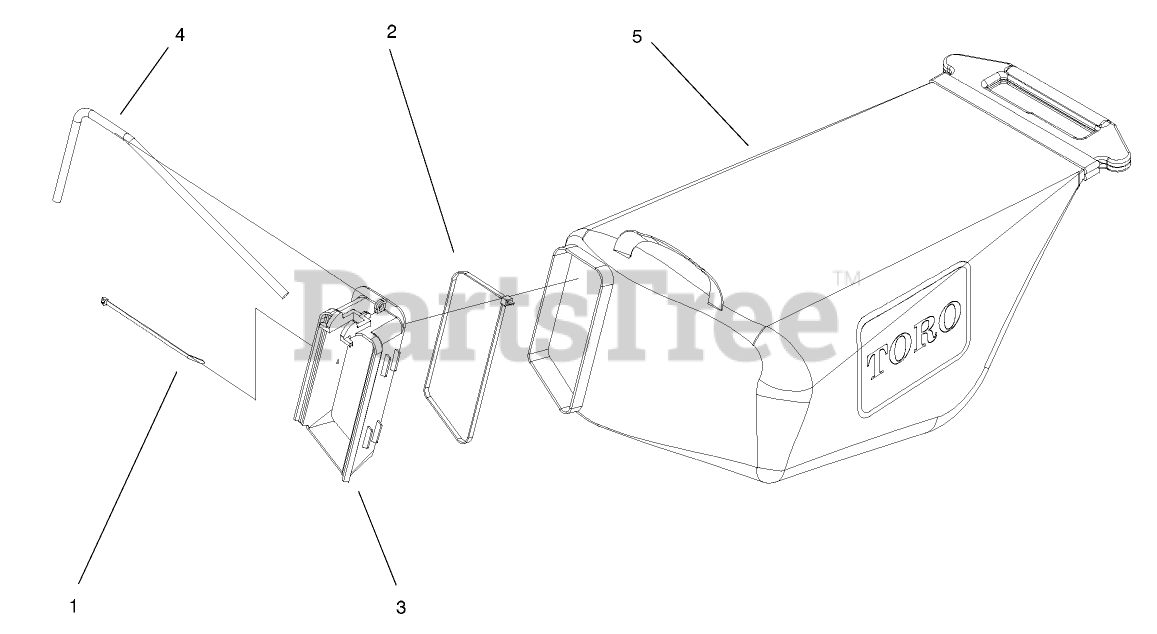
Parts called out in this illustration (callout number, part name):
1	TIE-CABLE
2	STRAP-TIE
3	Chute-Bag,Inlet
4	WIRE-SUPPORT,BAG
5	Bag-Grass,Ts
